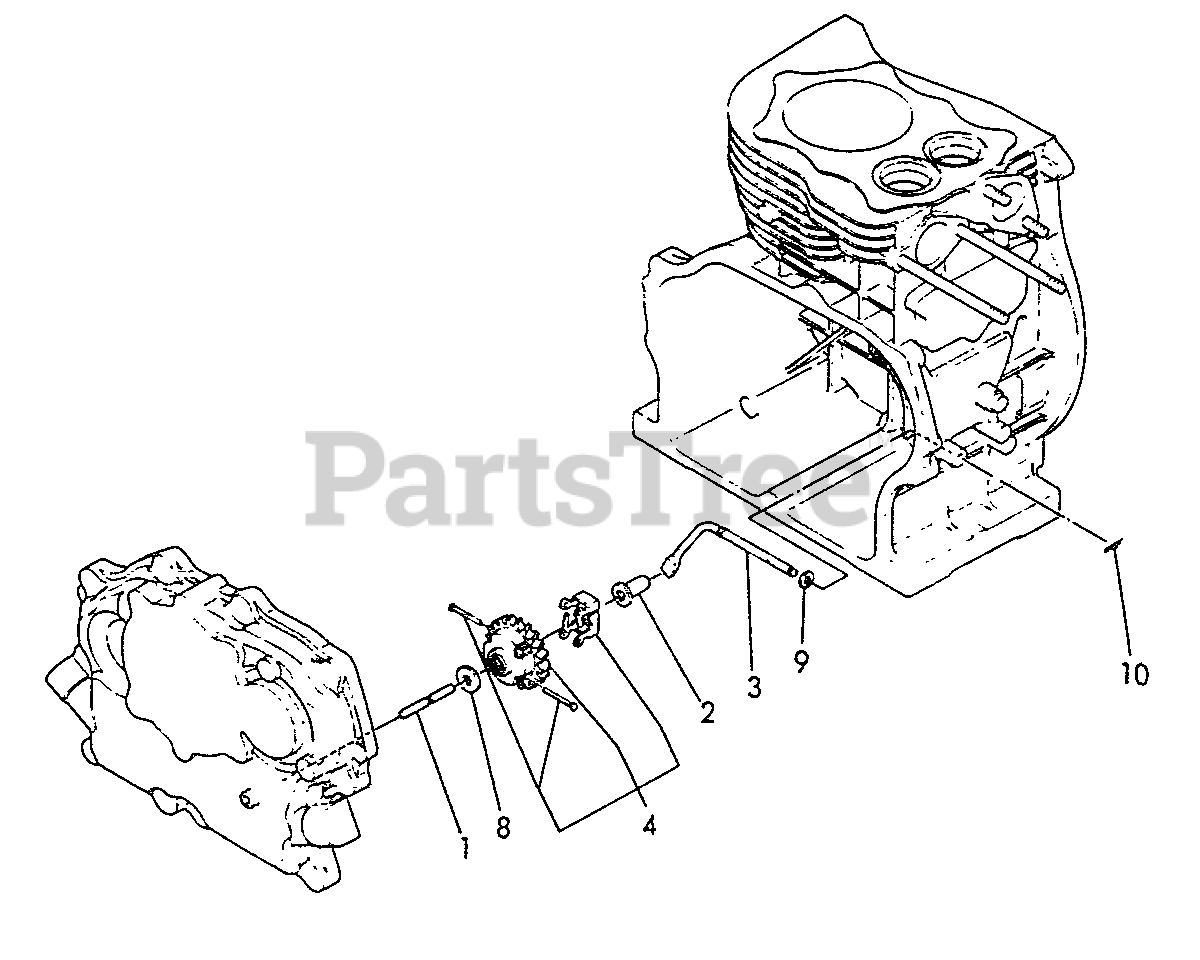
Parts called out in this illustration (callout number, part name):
1	SHAFT, GOVERNOR
2	SPINDLE, GOVERNOR
3	SHAFT, SHIFT LEVER
4	GOVERNOR GEAR ASSY
8	WASHER - 6
9	WASHER - 8
10	PIN - 8 -- SNAP
